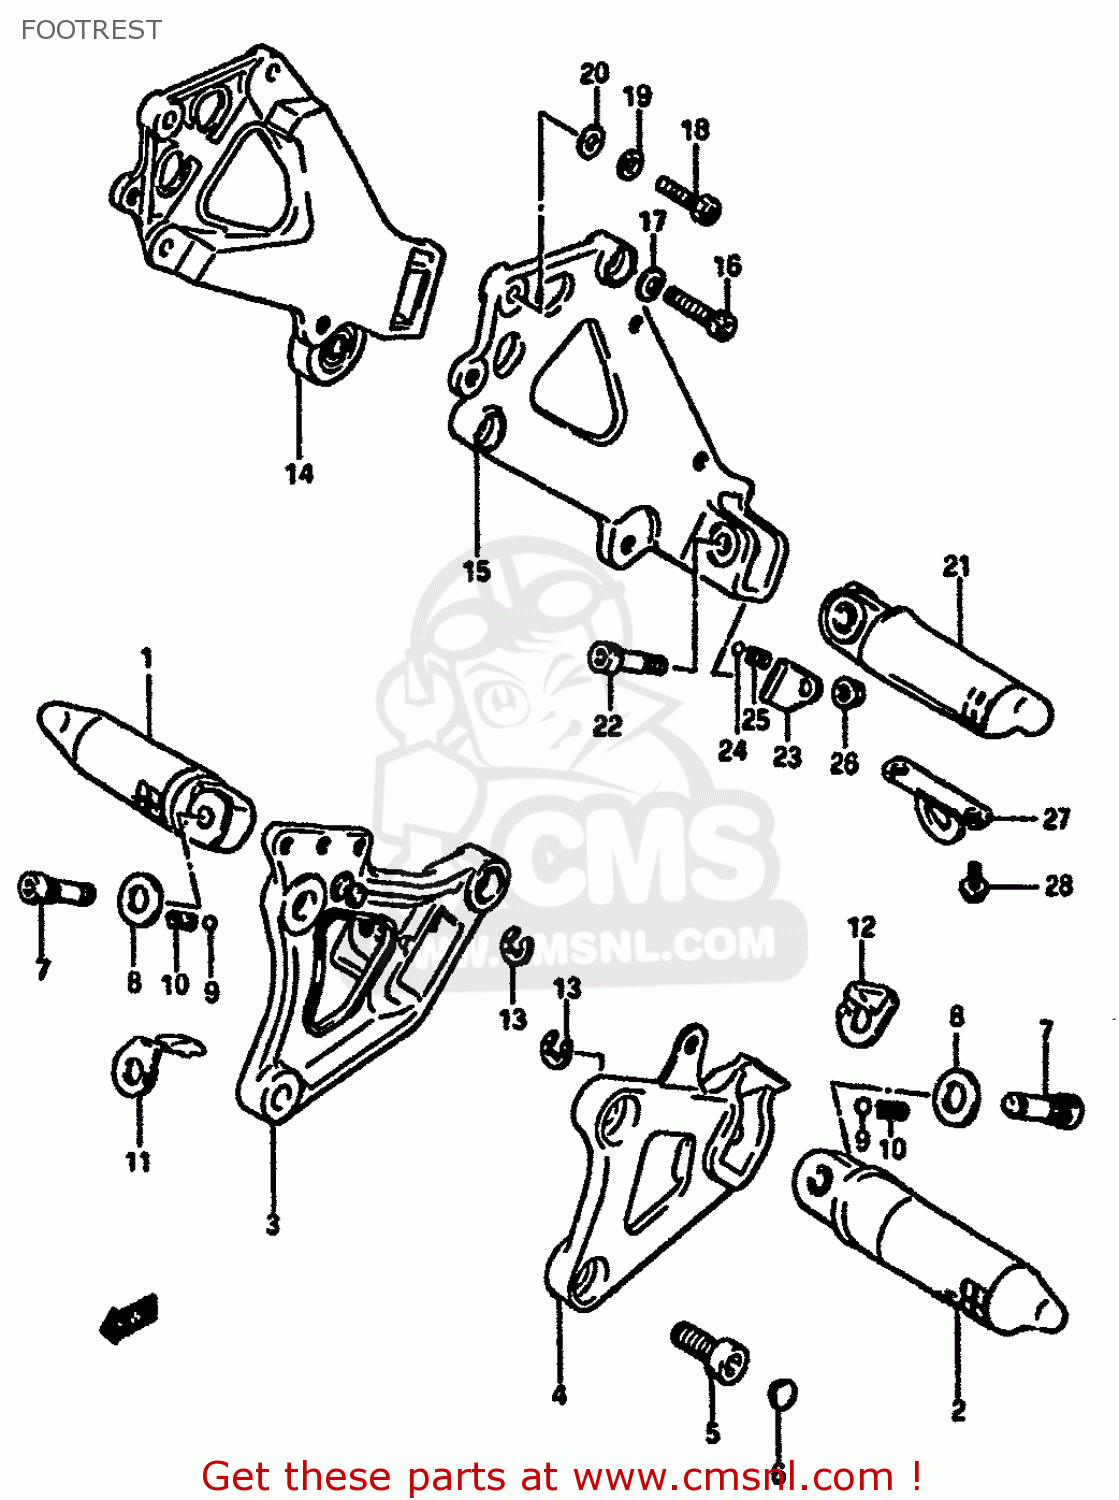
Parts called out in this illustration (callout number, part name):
1	FOOTREST ASSY,FR,R
2	FOOTREST ASSY,FR,L
3	BRACKET,FOOTREST,R
4	BRACKET,FOOTREST,L
5	BOLT
6	CAP
7	BOLT,FR FOOTREST
8	PLATE,SPRING STOP
9	BALL
10	SPRING
11	CUSHION,FRONT FOOTREST,RIGHT
12	CUSHION,FRONT FOOTREST,LEFT
13	E RING 6MM
14	BRACKET
15	BRACKET
16	BOLT
17	WASHER
18	BOLT 6X30
19	WASHER,LOCK
20	WASHER
21	FOOTREST ASSY,PILLION RH
22	BOLT,PILLION FOOTREST
23	PLATE,SPRING STOP LH
24	BALL
25	SPRING
26	NUT
27	HOOK
28	SCREW
